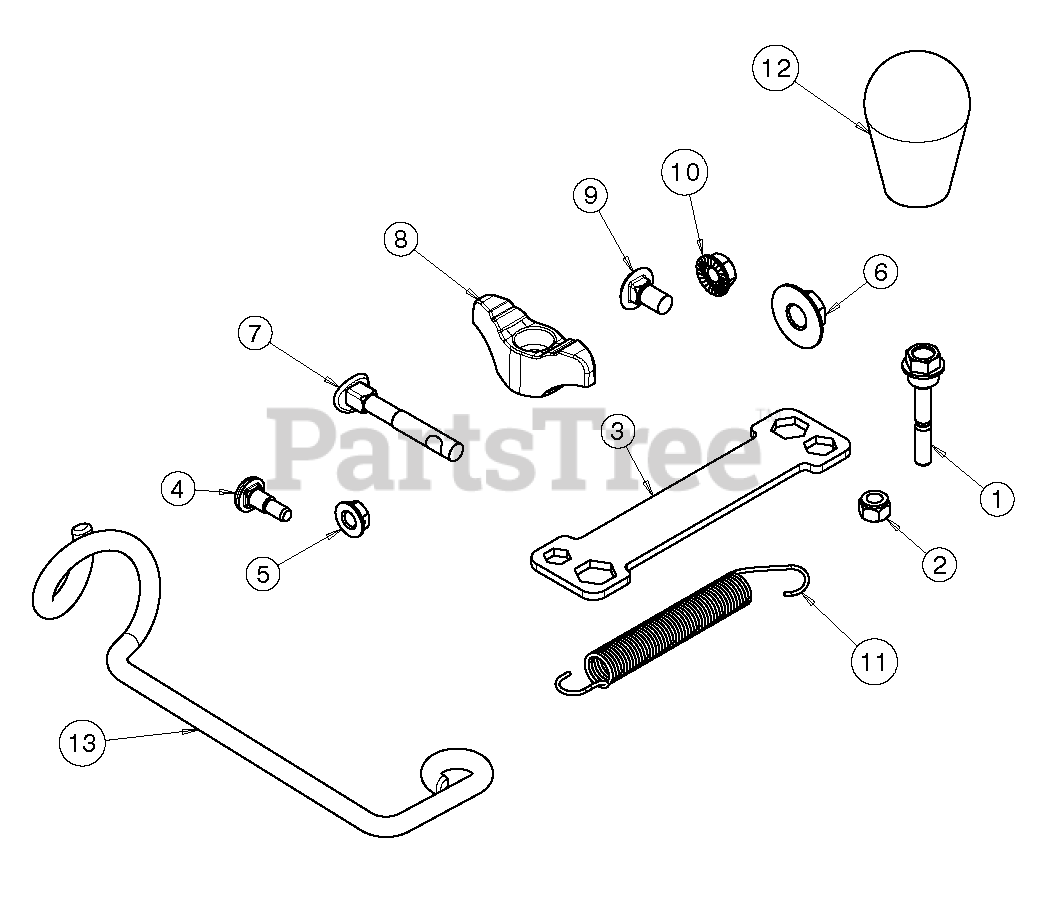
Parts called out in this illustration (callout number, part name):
1	Hex Head Shear Bolt, 1/4-20 X 1-13/16
2	LOCKNUT
3	WRENCH.SNOWTHROWER
4	Shoulder Bolt, 1/4
5	Flange Hex Lock Nut, 1/4-20 Large
6	Flange Hex Lock Nut, Black 3/8-16
7	Carriage Bolt, 5/16-18 X 2.25
8	KNOB, DEFLECTOR
9	Carriage Bolt, 5/16-18 X 5/8 Black
10	LOCKNUT-FLANGE 5/16-18
12	Knob, Soft Touch Slotted 428
13	Cable Rotation Support
